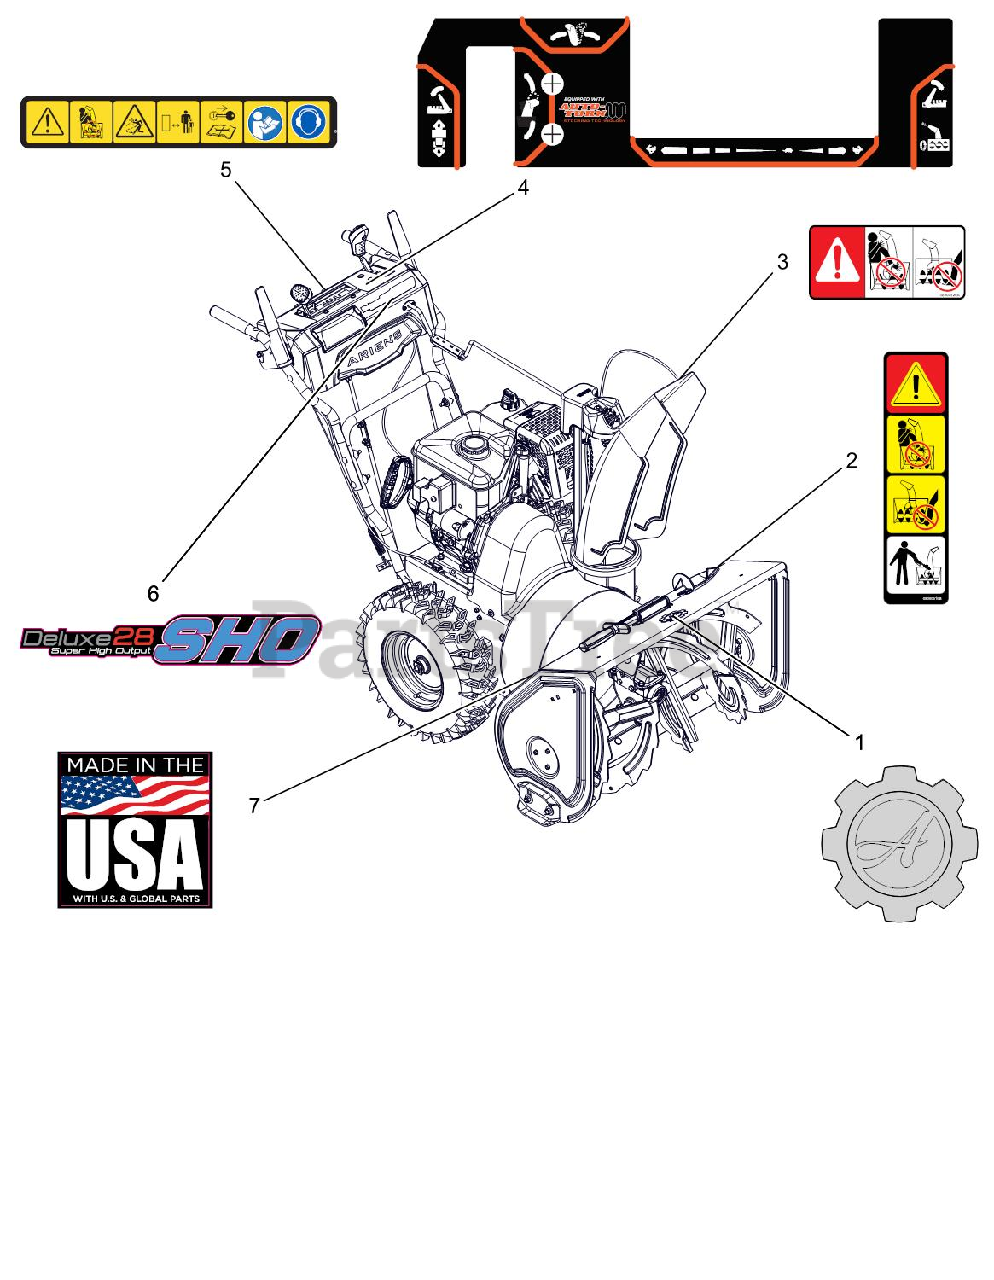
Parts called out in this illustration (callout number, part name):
1	DECAL, ARIENS-GEAR BADGE
2	DECAL, DANGER - ROTATING PARTS
3	DECAL, DANGER
4	DECAL,CONTROL-SML,AT,ID
5	DECAL,DASH - SAFETY
6	DECAL,SMALL DASH-DLX 28 SHO
7	DECAL, MADE IN USA
